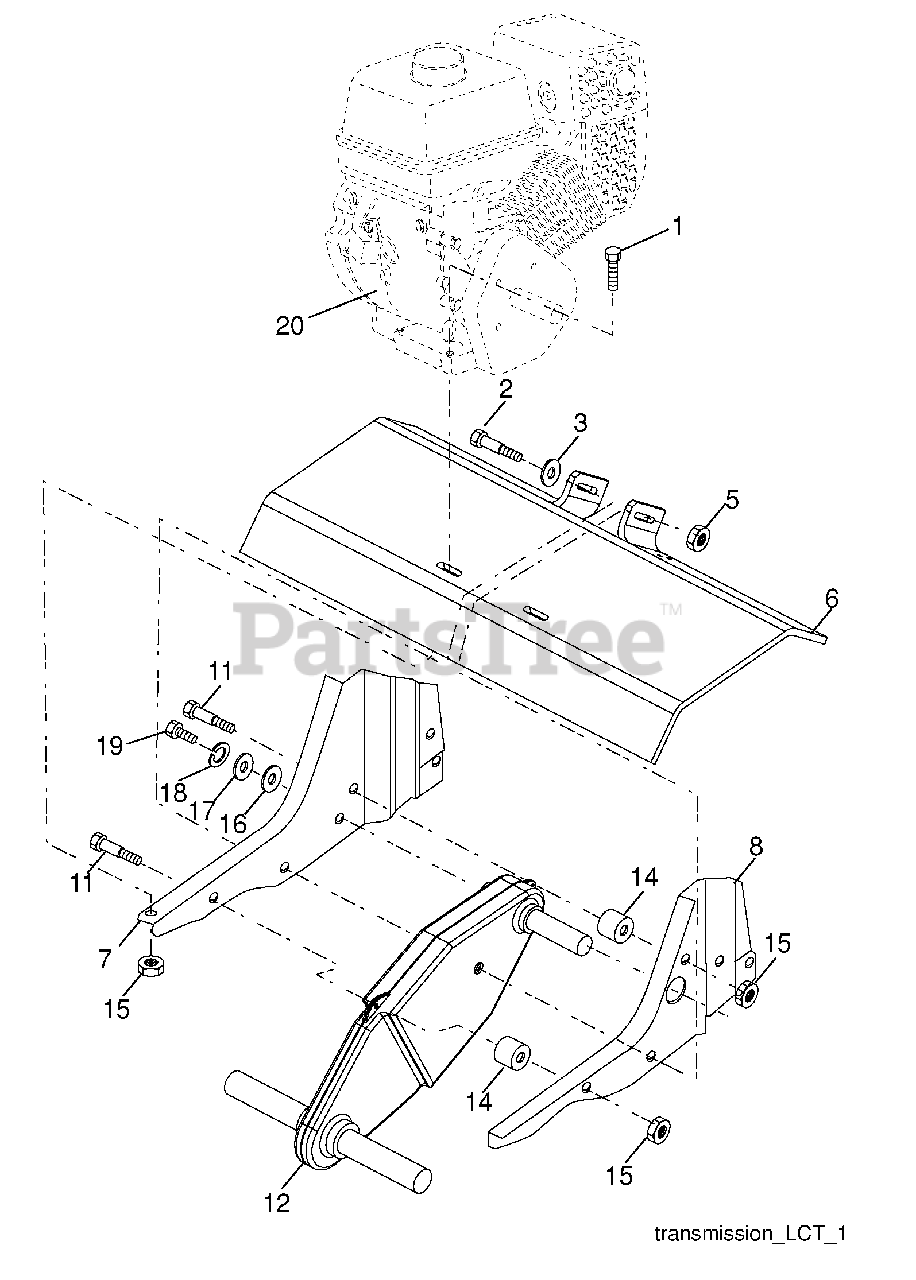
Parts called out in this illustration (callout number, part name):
1	Bolt, Hex 5/16-18 x 1-1/2 Gr. 2
2	Bolt, Fin, Hex 3/8-16 unc x 3.25
3	Washer 13/32 x 13/16 x 11 Ga.
5	Nut Lock Flg. 3/8-16 unc
6	Shield, Tine
7	Bracket, Engine, R.H.
8	Bracket, Engine, L.H.
11	Bolt, Shoulder 5/16-18 unc x 2.5
12	Transmission
14	Spacer, Split
15	Nut, Lock Hex Flange 5/16-18 unc
16	Washer 9/32 x 7/8 x 12 Ga.
17	Washer 9/32 x 1-1/4 x 16 Ga.
18	Washer, Lock 1/4
19	Bolt, Hex 1/4-28 x 3/4 Gr. 5
